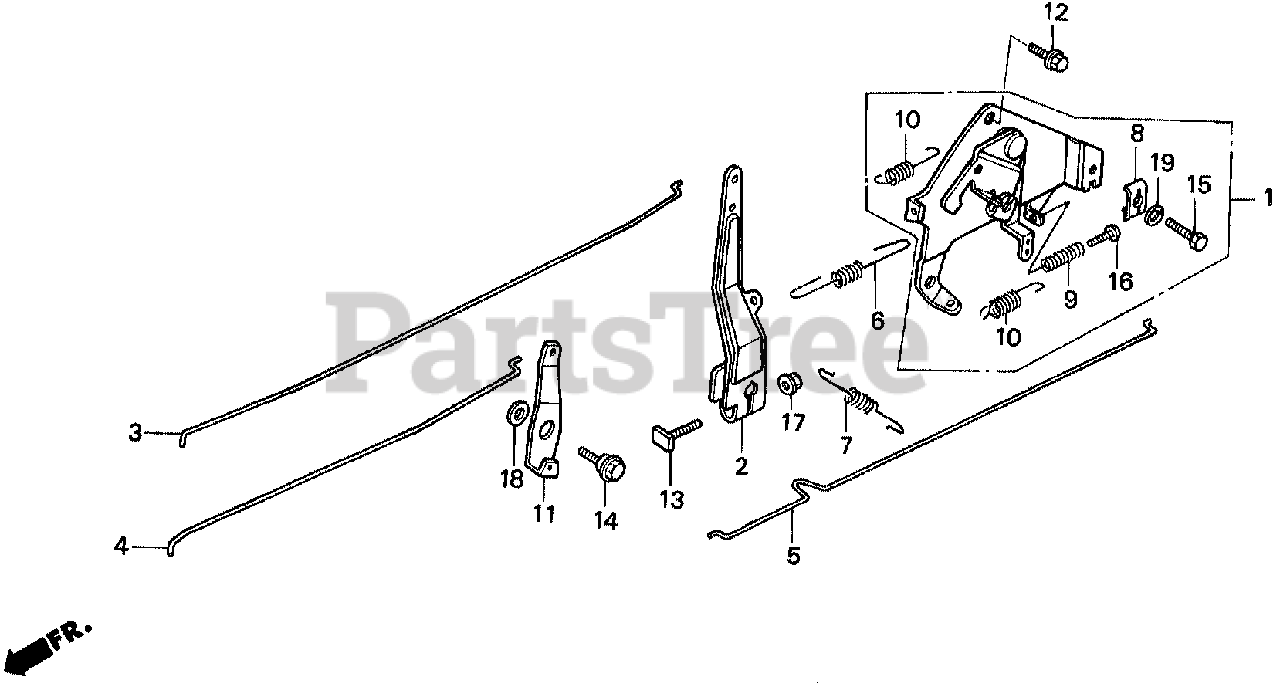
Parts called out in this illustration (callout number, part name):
1	CONTROL ASSY.
2	ARM, GOVERNOR
3	ROD, GOVERNOR
4	ROD, CHOKE
5	ROD, JOINT
6	SPRING, GOVERNOR
7	SPRING, GOVERNOR PRIMARY
8	HOLDER, CABLE
9	SPRING, CONTROL ADJUSTING
10	SPRING, CABLE RETURN
11	LEVER, CHOKE JOINT
12	BOLT, FLANGE (6X12) (CT200)
13	BOLT, GOVERNOR ARM
14	BOLT, FLANGE (6MM)
15	BOLT, RECESSED (5X16)
16	SCREW, PAN (5X20)
17	NUT, FLANGE (6MM)
18	WASHER, PLAIN (6MM)
19	WASHER, SPRING (5MM)
